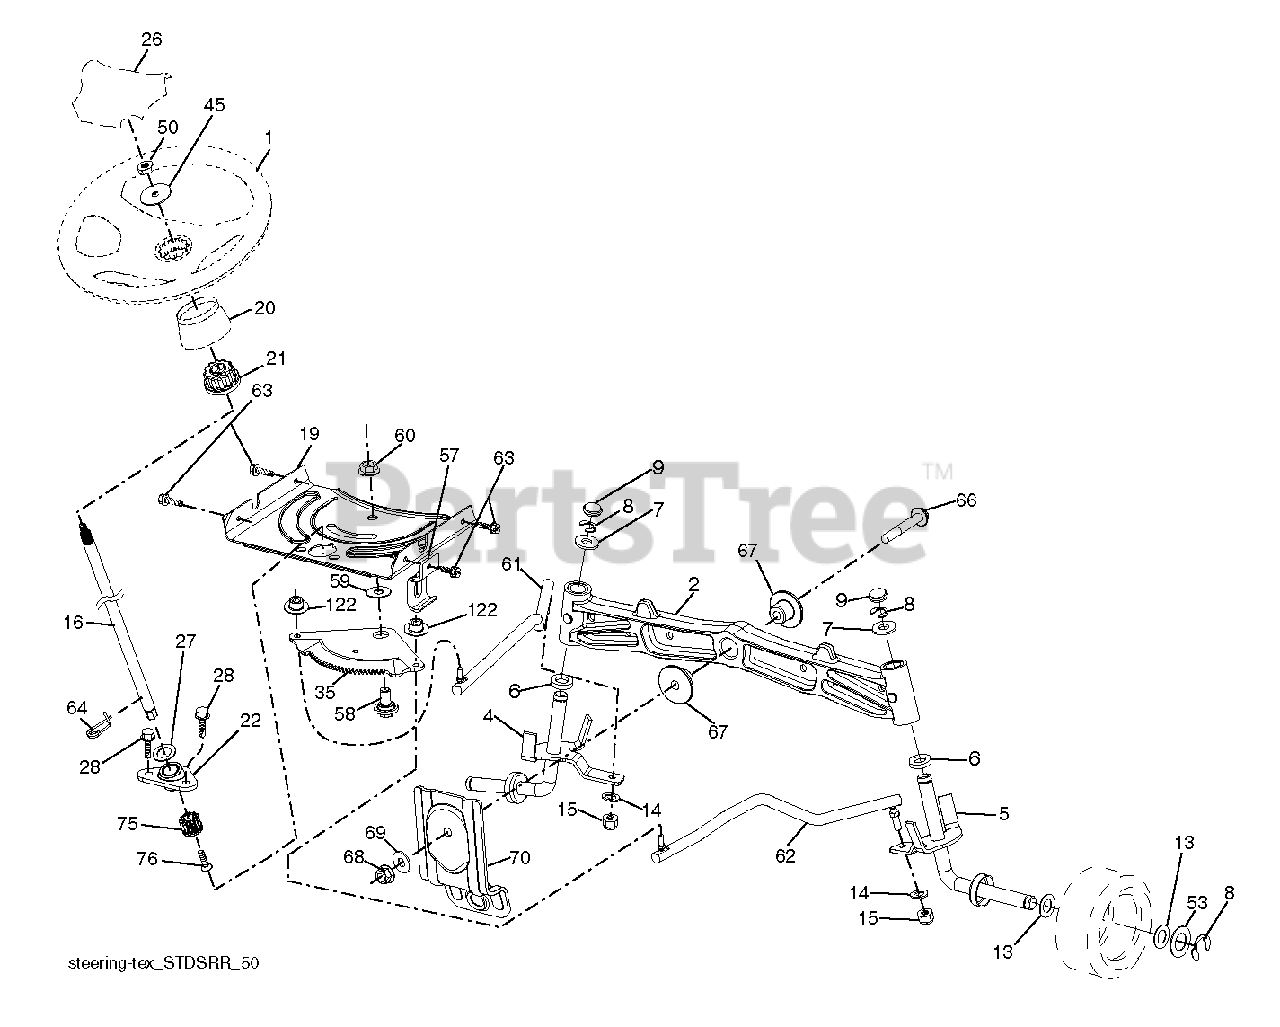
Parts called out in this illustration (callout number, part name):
1	WHEEL.STEERING.STDSRR.BLK/OV
2	AXLE.CAST.IRON
4	SPINDLE.WELDED.LH.16"TEX
5	SPINDLE.WELDED.RH.16"TEX
8	RING CLIP
9	CAP.SPINDLE
14	WASHER, LOCK 3/8
15	NUT CROWNLOCK 3/8-24
16	Steering Shaft Service Kit
19	PLATE.STEER.DDL.NLT/NG
21	Steering Shaft Adapter Kit
22	Steering Shaft Service Kit
26	CAP.WHL.STRNG.STDSRRD.SRS.BLK
27	WASHER LT
28	SCREW, 3/8-16X3/4
35	GEAR.SECTOR.PLATE.DDL.
45	WASHER.3/8ID.2-3/8OD.12GA.PLTD
50	NUT LOCK FLG 3/8-16 UNC
53	WASHER.HARDENED
57	BRKT.UPSTOP.GT/LT.TEX
58	BOLT.SHOULDER.SECTOR.P
59	WASHER.THURST.SECTOR.S
60	NUT FLANGE LOCK 5/8-11
61	DRAGLINK.LH.BALLSTUD.D
62	DRAGLINK.RH.BALLSTUD.D
63	SCREW
64	RETAINER.CLIP.SPRING.S
66	BOLT HEX FGHD 7/16-14 X 3 SERR
67	BUSHING.PM.FRONT AXLE
68	NUT.LOCK.FLANGE.7/16
69	WASHER.1.5X.505X.118
70	Deck Suspension Bracket, Front RR
75	Steering Shaft Pinion Kit
76	Screw Head Socket Lrvb
